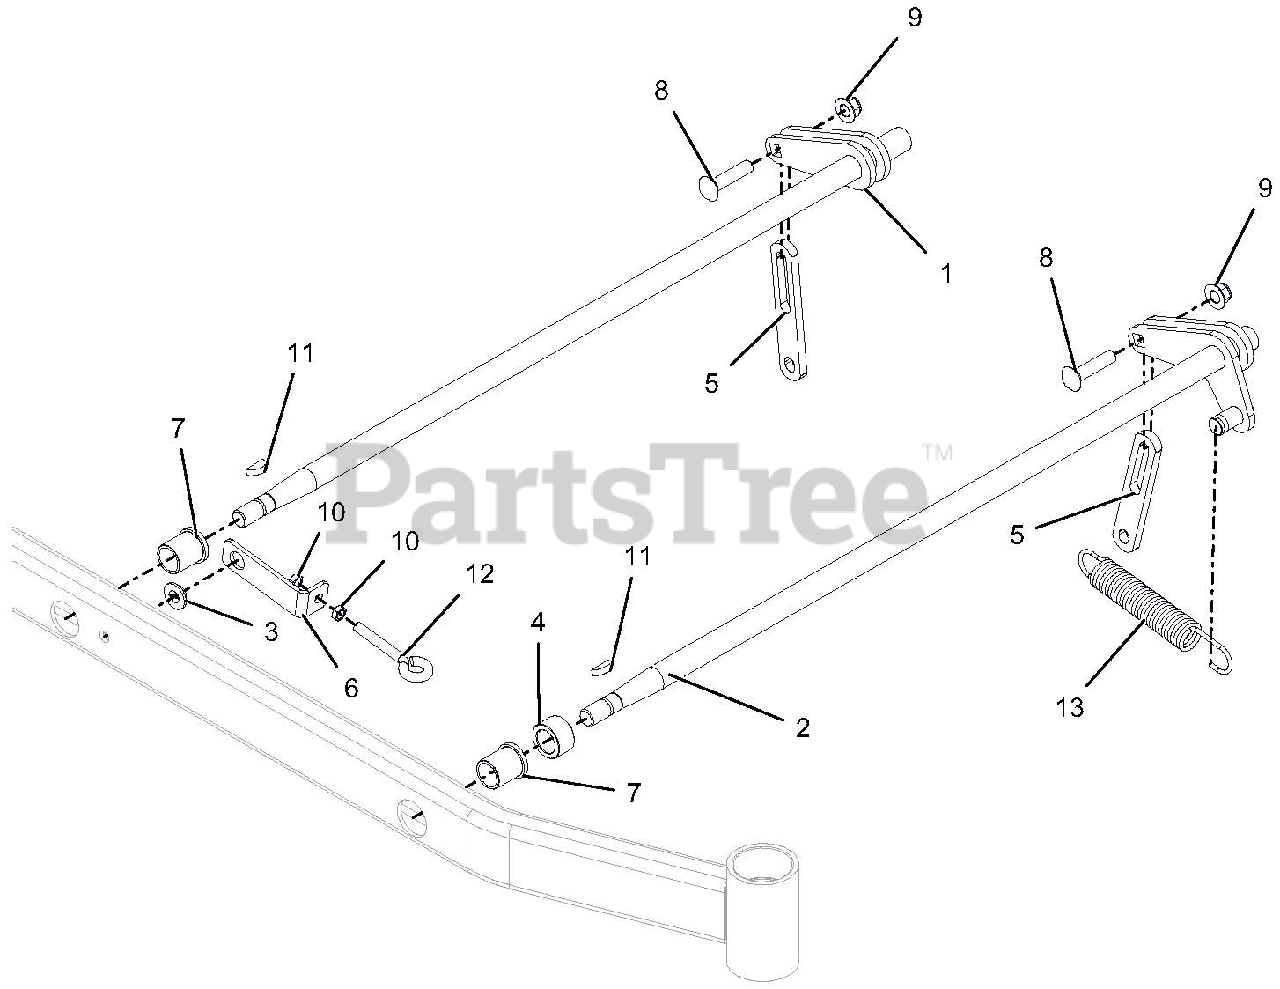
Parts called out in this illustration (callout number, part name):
1	WLDMT, REAR LH DECK LIFT ARM
2	WLDMT, FRONT LH DECK LIFT ARM
3	BSHG, FLANGE .515X.750X.31X1.12
4	SPACER, 1.500 X 1.000 X .880
5	LINK, DECK LIFT - LONG
6	BRKT, SPRING ANCHOR
7	BSHG-FLG 1.00X1.25X1.5X1.5
8	BLT-RDHDSQNK .50-13X2.25 G5 Y
9	NUT-LK-NYL-FLG .50-13 YWZC
10	NUT, JAM .375-16 YWZC
11	KEY, WDRF .25 X 1.00 HRD #15
12	BOLT, EYE .375-16
13	SPRG, TENSION .162 X 1.250 X 8.250
